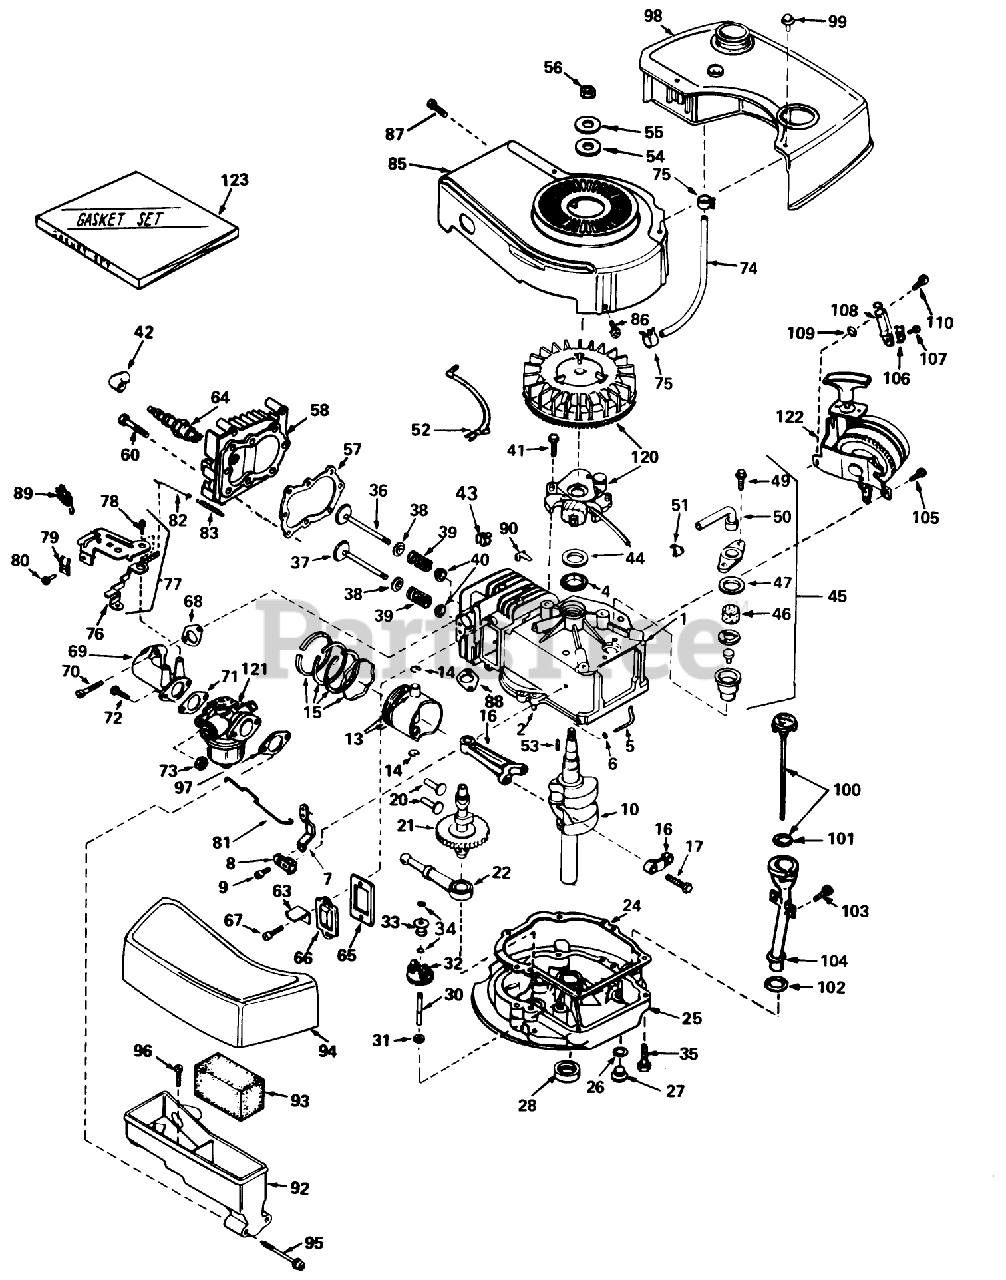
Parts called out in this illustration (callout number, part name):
1	Cylinder Assy. (Incl. Ref. #2, 4 105)
2	Pin-Dowel
4	OIL SEAL
5	Rod, Governor (Incl. No. 36)
6	Washer-Flat
7	Governor Lever
8	Clamp-Lever, Governor
9	Screw
10	Crankshaft
13	Piston, Pin Ring Assy. (Incl.Ref. #14 15)(Std.)
13	Piston, Pin Ring Assy. (Incl. #14 15)(.010 oversize)
13	Piston, Pin Ring Assy. (Incl.Ref. #14 15) (.020 oversize)
14	Ring-Retaining, Piston Pin
15	Ring Set Piston (Std.)
15	Ring Set Piston (.010 Oversize)
15	Ring Set Piston (.020 Oversize)
16	Rod Assy., Connecting (Incl. Ref. #17)
17	Bolt-Rod, Connecting
20	Lifter-Valve
21	Camshaft(Mech.Comp. Release)
22	Oil Pump ASM
24	Gasket, Mounting
25	Flange Assy., Mounting (Incl. Ref. #26thru 30)
26	Gasket-Oil Drain
27	Plug Oil Drain
28	Seal Oil
30	Shaft-Governor
31	Washer-Flat
32	Governor Gear ASM
33	Spool-Governor
34	Ring-Retaining
35	Screw (1/4-20 x 1-1/4)
36	Valve, Intake (Incl. Ref. #38, 39 40) (Std.)
36	Valve, Exhaust (1/32" Oversize) (Incl. Nos. 8, 9 10)
37	Valve, Exhaust (Standard) (Incl. Nos. 8, 9 10)
37	Valve, Exhaust (1/32" Oversize) (Incl. Nos. 8, 9 10)
38	Cap-Upper Valve Spring
39	Spring-Valve
40	Cap-Valve, Spring
41	Screw
42	Cover-Spark Plug
43	51004 GIL ROTARY TI
44	Gasket Stator
45	Breather Assy. (Incl. Ref. #46, 47, 49, 50 51 )
46	Element-Breather
47	Gasket-Breather
49	Screw, Hex Hd. w/Conical
50	Tube, Breaker
51	Clip, Breather
52	Wire Ground
53	Key-Flywheel
54	Washer Flat
55	Washer-Spring
56	Hex Nut
57	63573 GIL 42 SNWTHW
58	Head-Cylinder
60	Screw (5/16-18x1-1/2)
63	Retainer Clip
64	Plug, Spark (J17LM or equiv.)
64	Plug, Spark (Champion RCJ-8)
65	Gasket-Breather
66	Cover-Valve
67	Screw
68	Gasket, Intake
69	Pipe, Intake
70	Screw (1/4-20 x 1)
71	Gasket-Carburetor
73	Nut and Lock Washer (1/4-28)
74	Line-Fuel
75	Clamp-Line, Fuel
76	Lever Control
77	Control Assy., Speed (Incl. Nos, 76, 78 89)
78	Screw, Hex Washer Hd Shoulder Self-Tap
79	Conduit
80	Screw (10-32 x 3/8)
81	Link-Throttle
82	Link Governor Spring
83	Spring Governor
85	Housing Blower
86	Screw
87	Screw (10-24 x 9/16)
88	Gasket Exhaust
89	Terminal
90	Clip-Wire
92	Body Air Cleaner
93	Filer, Air
94	Cove, Air Cleaner
95	Screw Fil Hd.
96	Screw, Hex Hd.
97	Gasket-Air Cleaner
98	Tank, Fuel
99	Screw (10-32 x 35/64)
100	Dipstick, Oil (Incl. Ref. #101)(Twist Lock)
101	O-Ring
102	Gasket
103	Screw (10-32 x 1/2)
104	Tube-Oil Fill
105	Screw (1/4-20 x 1/2)
106	Conduit
107	Screw (10-32 x 3/8)
108	Bracker
109	Washer
110	Screw (1/4-20 X 5/8)
120	Magneto
121	Carburetor (Incl. Ref. #71 )
122	Starter
123	53024/VAR.16HP O/P
